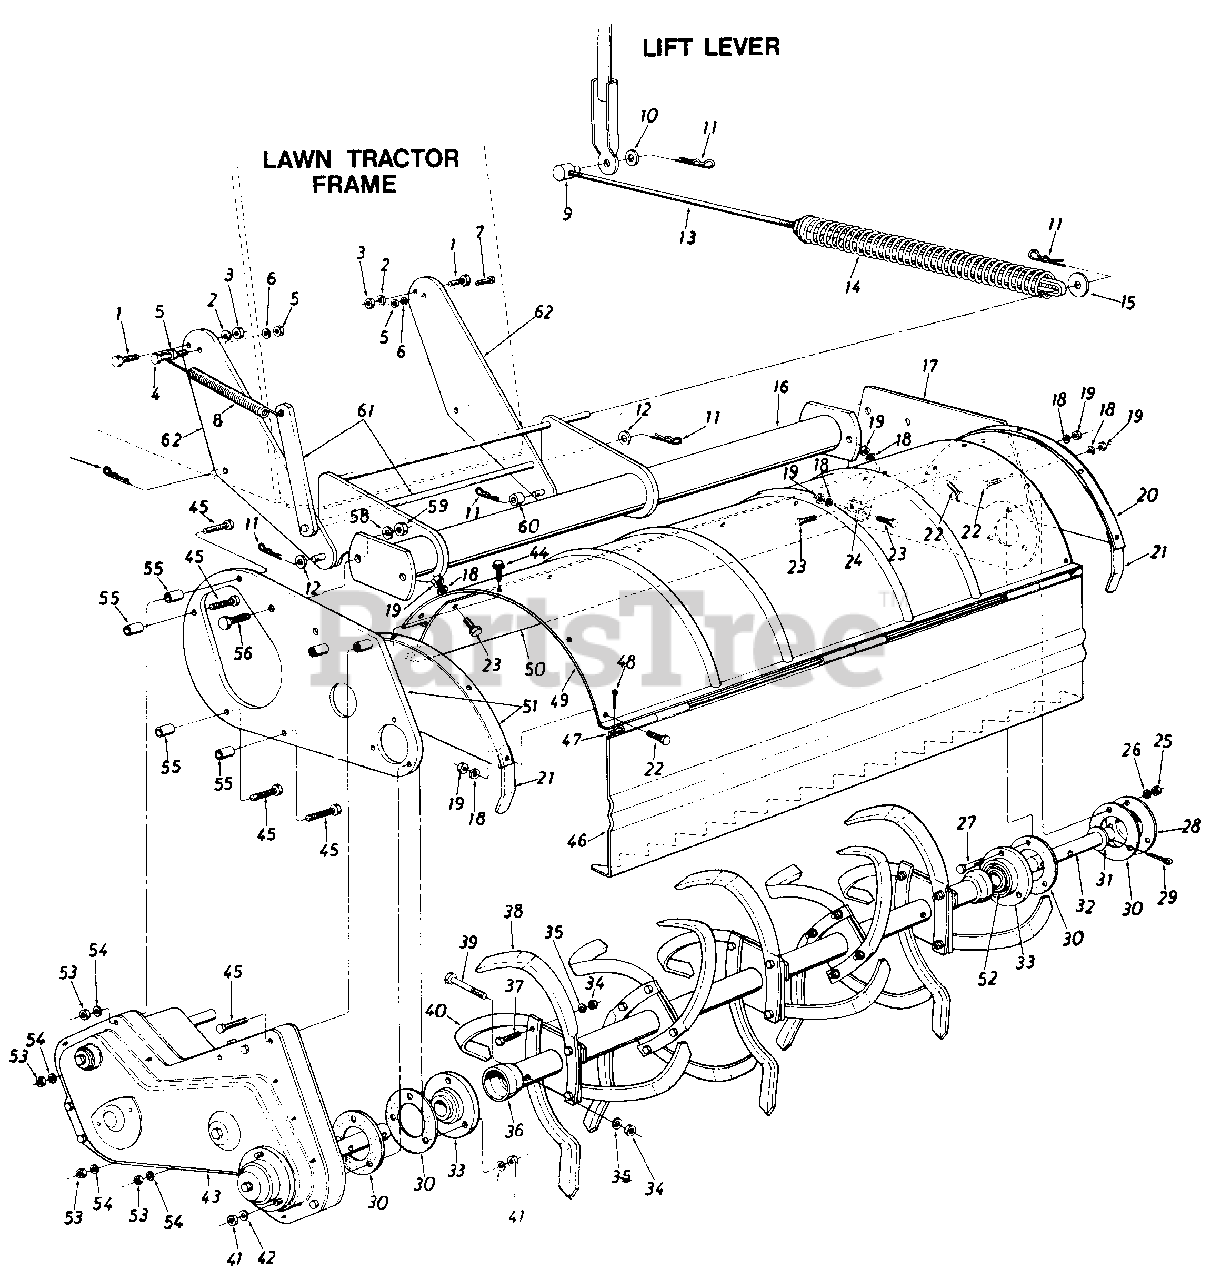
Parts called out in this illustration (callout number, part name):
1	Hex Bolt 3/8-24x .88" Lg.*
2	L.-Wash. 3/8" I.D. Heavy Duty
3	Hex Nut 3/8-24 Thd.*
4	Hex Bolt 5/16-24 x 1.50" Lg.*
5	Hex Nut 5/16-24 Thd.*
6	L.-Wash. 5/16" I.D.*
7	Hex Bolt 5/16-24 x 1.00" Lg.*
8	Extension Spring .56" O.D. x 7.75" Lg.
9	Adjustment Ferrule 1/2-13 Thd.
10	Fl.-Wash. .640" I.D. x 1.24" O.D. x .060
11	Intern. Cotter Pin 1/2" Dia.
12	Fl.-Wash. .510" I.D. x 1.0" O.D. x .060
13	Lift Rod Ass'y. 39.0" Lg.
14	Compression Spring 1.50" O.D. x 15.0" Lg.
15	Fl.-Wash. .51" I.D. x 1.50" O.D. x .075
16	Pivot Bracket Assembly
19	Hex Nut 5/16-24 Thd.*
23	Hex Bolt 5/16-24 x .62" Lg.*
24	Chute Pivot Bracket
25	Hex Cent. L-Nut 5/16-18 Thd.
26	L.-Wash. 5/16" I.D.*
27	Hex Bolt 5/16-18 x 1.0" Lg. (Grade 5)
30	Gasket for Brg. Housing
31	Fl.-Wash. 1.25" I.D. x 2.00" O.D x .06
32	Tine Shaft R.D. 1.25" Dia. x 6.25" Lg.
33	Bearing Housing w/Bearing
34	Hex Nut 3/8-24 Thd.*
35	L.-Wash. 3/8" I.D. Heavy Duty
41	Hex Cent. L.-Nut 5/16-18 Thd.
42	L.-Wash. 5/16" I.D.*
43	Chain Case Ass'y. Comp.
44	Hex Wash. TT Tap. Scr. 5/16-18 x .62" Lg.
45	Hex Bolt 1/4-20 x 2.75" Lg.*
48	Cotter Pin 1/8" Dia. x 1.00" Lg.*
53	Hex Nut 1/4-2 Thd.*
54	L.-Wash. 1/4" I.D.*
55	Spacer .28" I.D. x .62" O.D. x .90" Lg.
56	Hex Bolt 1/2-13 x 1.00" Lg.*
58	L.-Wash. 1/2" I.D.*
59	Hex Nut 1/2-13 Thd.*
60	Spacer .50" I.D. x 1.00" O.D. x.50" Lg.
61	Idler Bracket Support Arm Ass'y.
62	Pivot Bracket Support
